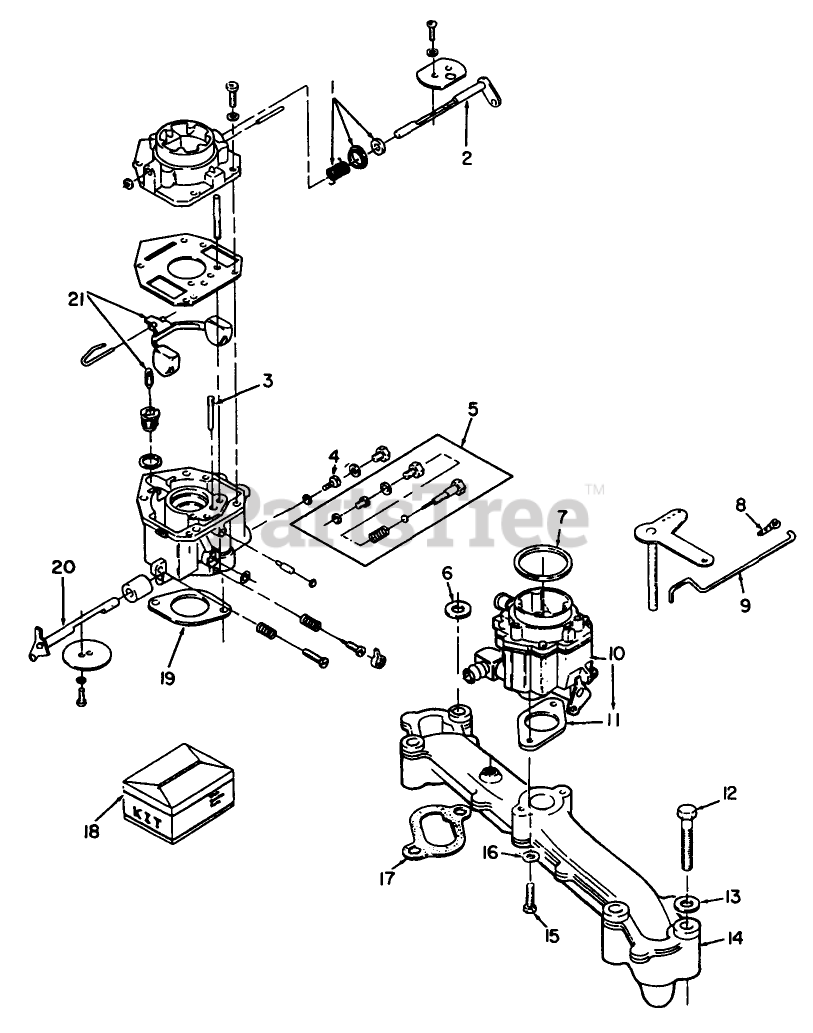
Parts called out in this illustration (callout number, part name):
1	CHOKE KIT LEVER
2	CHOKE KIT SHAFT
3	IDLE JET
4	POWER JET
5	Kit-Variable Jet
6	WASHER-PLAIN
9	CONTROL ROD
10	Carburetor-Complete
11	Gasket
12	SCREW-HH
13	WASHER-PLAIN
14	INTAKE MANIFOLD KIT
15	SCREW-HH
16	WASHER-FLAT
17	GASKET
18	Repair Kit
19	Gasket
20	Shaft-Throttle
21	FLOAT
